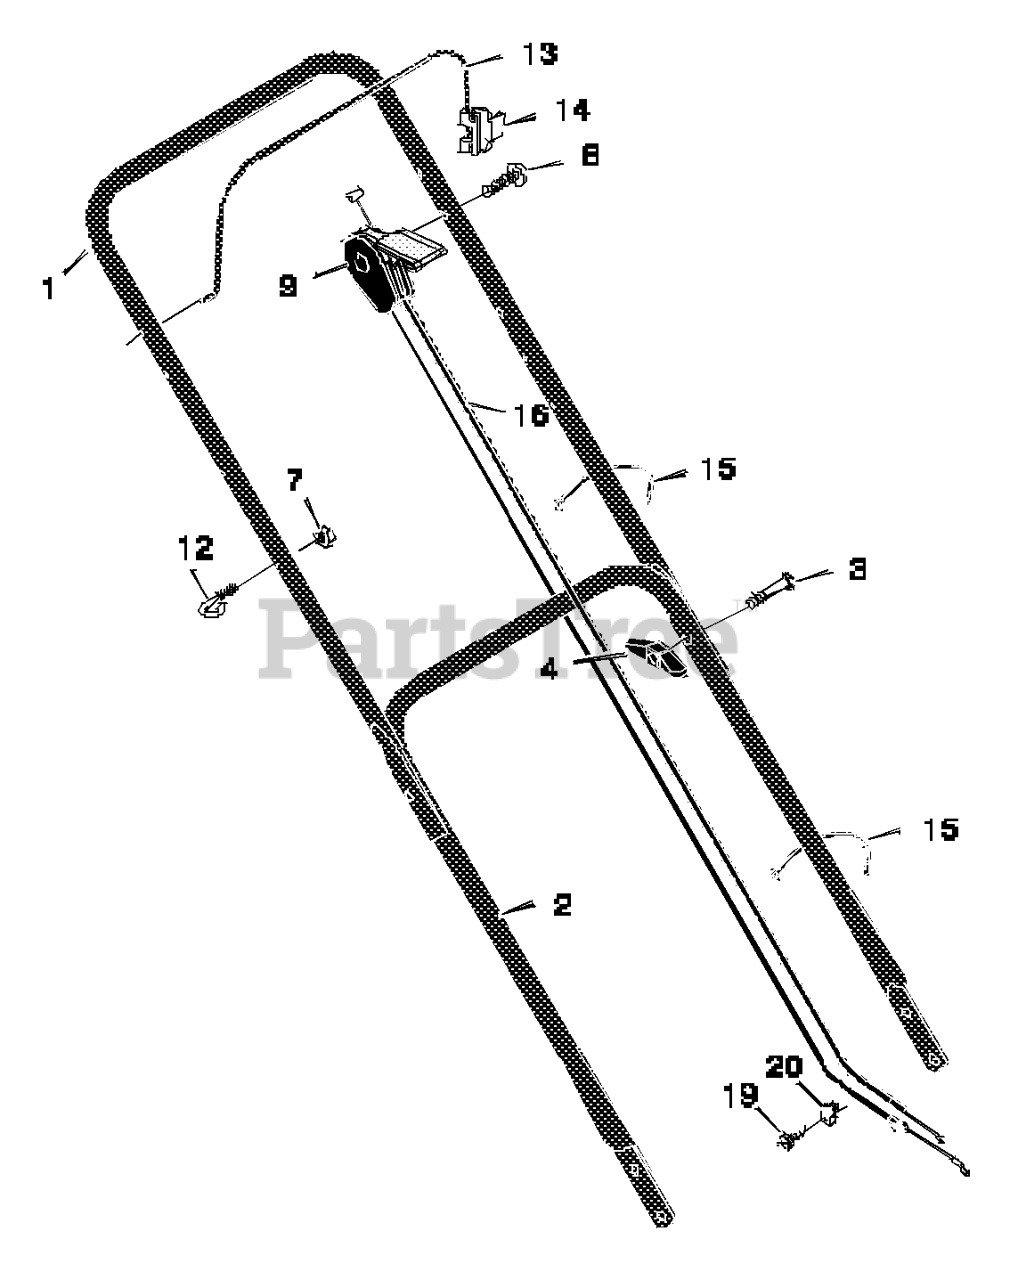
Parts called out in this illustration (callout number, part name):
1	Handle, Upper (Black)
2	Handle, Lower (Black)
4	Knob, Plastic
7	Locknut
9	Throttle Control
12	GUIDE, ROPE
13	Engine Stop Lever
14	Bracket, Stop Lever
15	Fastener, Cable
16	Engine Stop Cable
